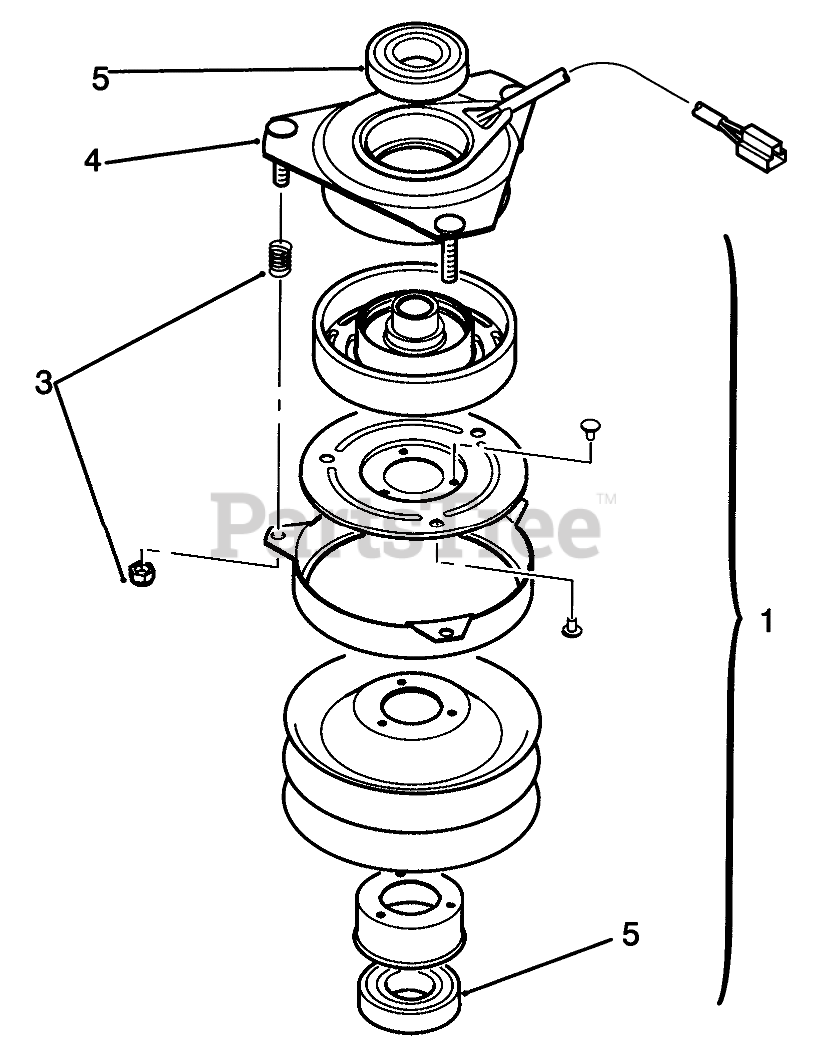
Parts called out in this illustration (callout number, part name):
1	ROTOR & ARMATURE ASSY
3	ACCESSORY PKG SRVC PART
4	Assembly-Field (Incl. Ref. #5)
5	BEARING-ELEC CLUTCH
